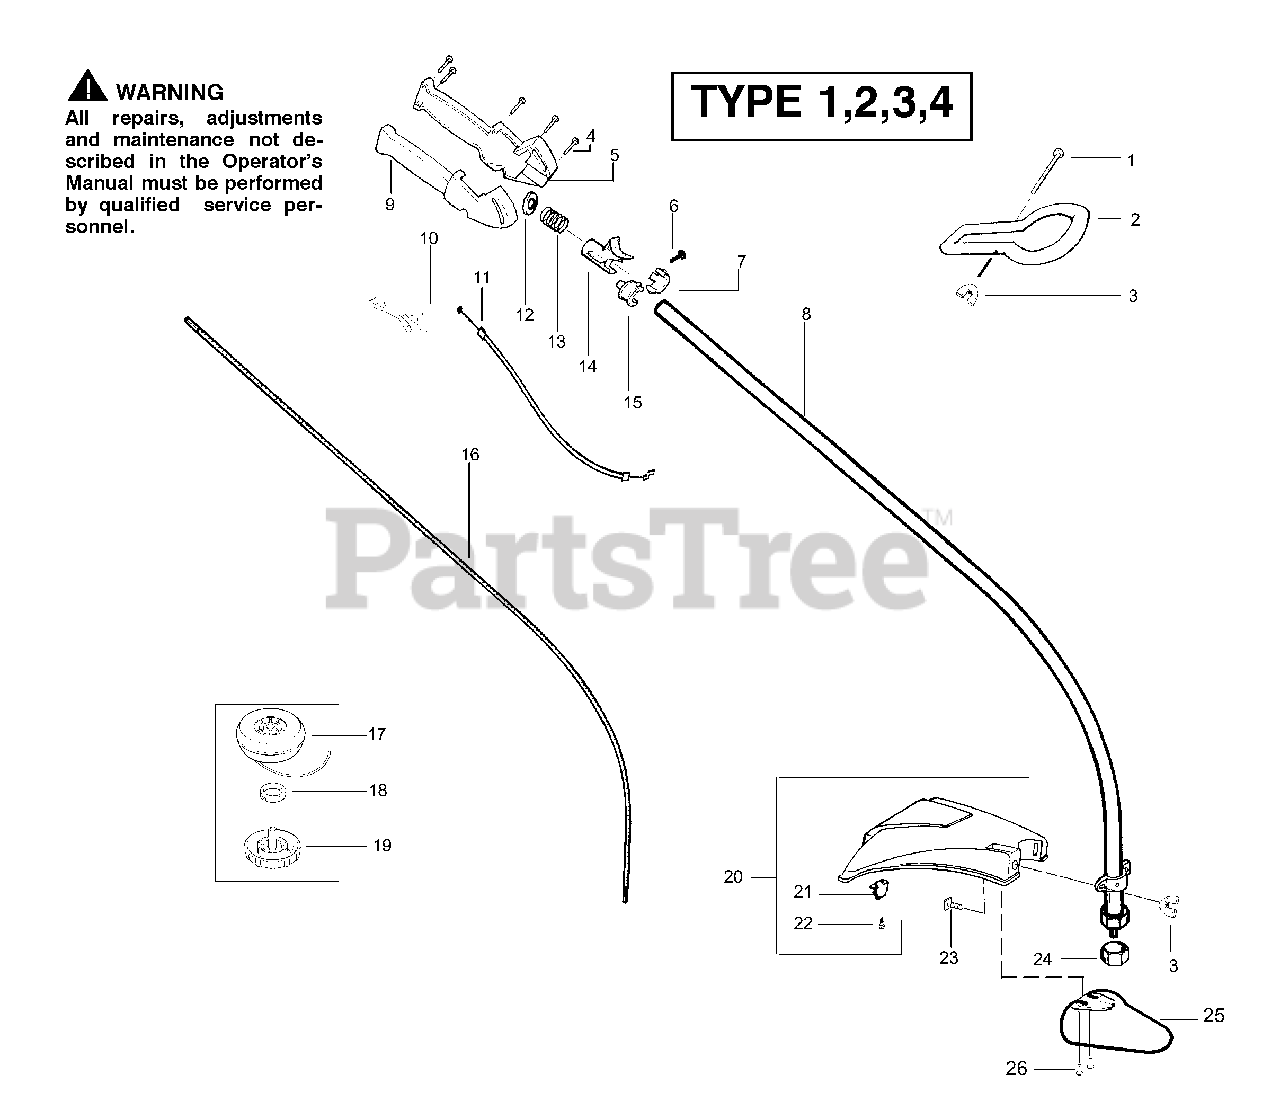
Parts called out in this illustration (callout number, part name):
1	Bolt-Handle
2	Assist Handle
3	Wingnut
5	Throttle Hsg. (Left)
6	Screw
7	Locator-Left
8	Drive Shaft Hsg. Ass'y
9	Throttle Hsg. (Right)
10	Trigger - Throttle
11	Assy-Throttle Cable (Type 1)
11	Assy-Throttle Cable (Type 2,3,4)
13	Spring-Compression
14	Actuator
15	Locator-Right
16	Drive Shaft - Flex
17	Assy. - Wound Hub
18	Guide - Line
19	Assy. - Cap 5/16"
20	Shield Kit Ass'y.
21	Line Limiter
22	Screw-Line Limiter
23	Bolt-Shield
24	Dust Cup
25	Assy-Wire Guard
